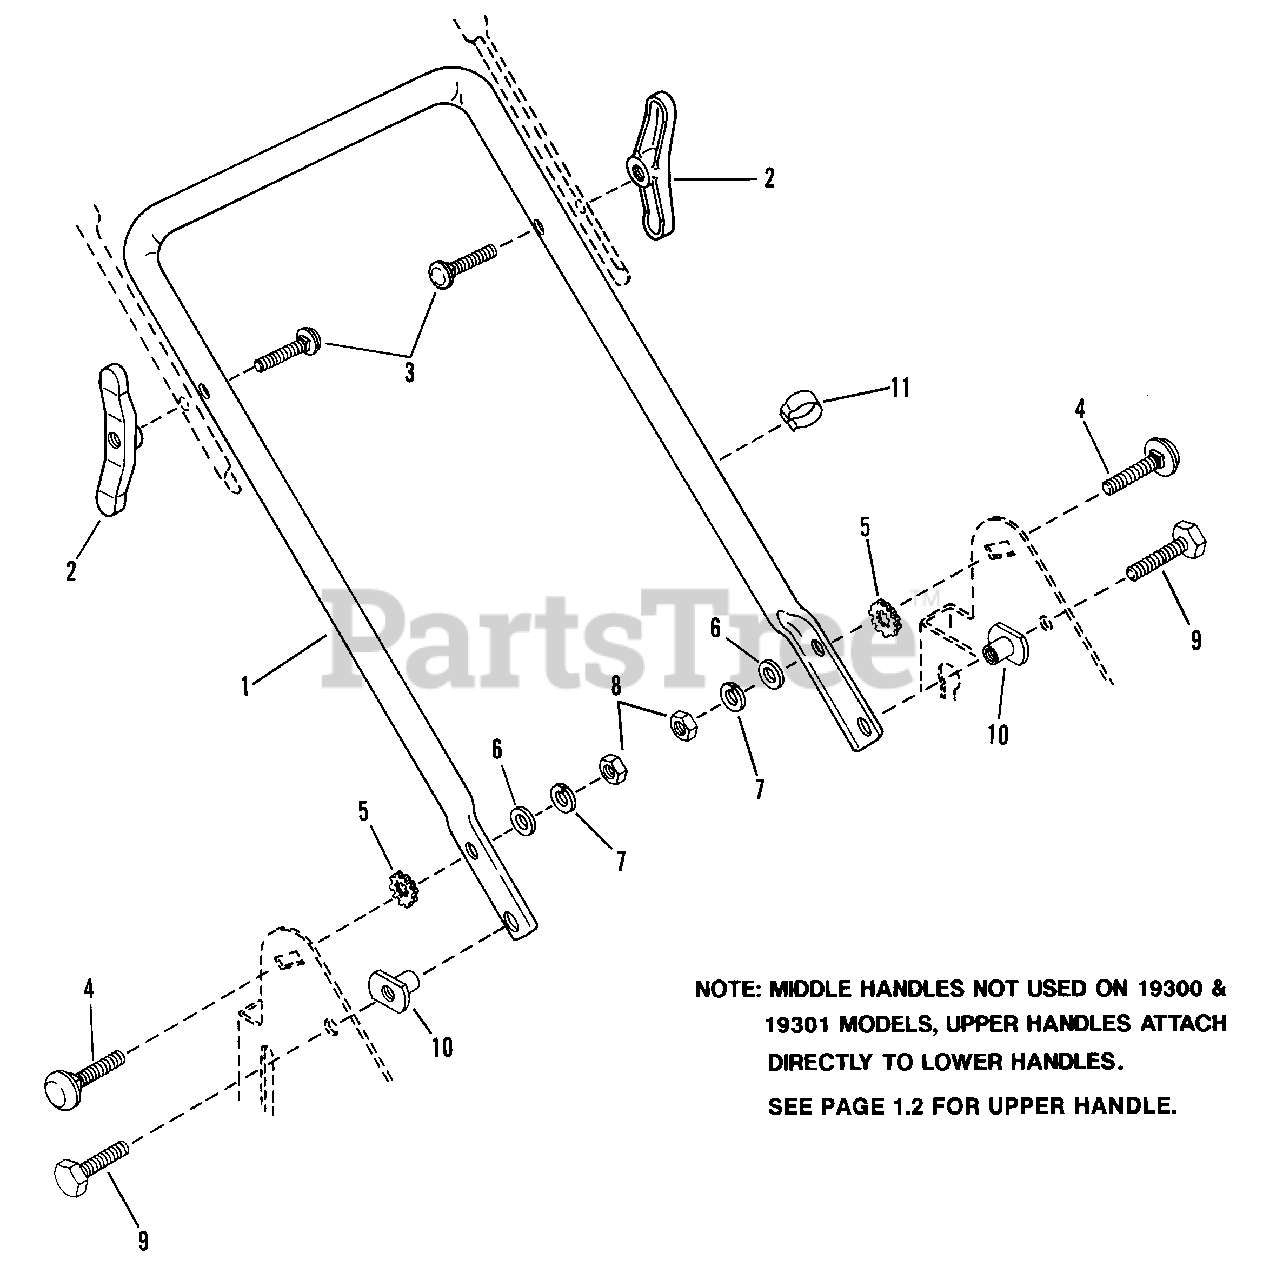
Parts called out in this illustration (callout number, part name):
1	HANDLE, Lower
2	NUT, 1/4-20 Wing
3	BOLT, 1/4-20 x 1-3/4" Square Neck Carriage
4	BOLT, 5/16-18 x 1" Short Neck Carriage, Grade 5
5	WASHER, 5/16" Internal/External Tooth Lock
6	WASHER, 5/16" Flat
7	WASHER, 5/16 Split Lock
8	NUT, 5/16-18 Hex
9	SCREW, 5/16-18 x 1/2" Hex head Cap, Grade 2
10	T-NUT, 5/16-18
11	CLIP
